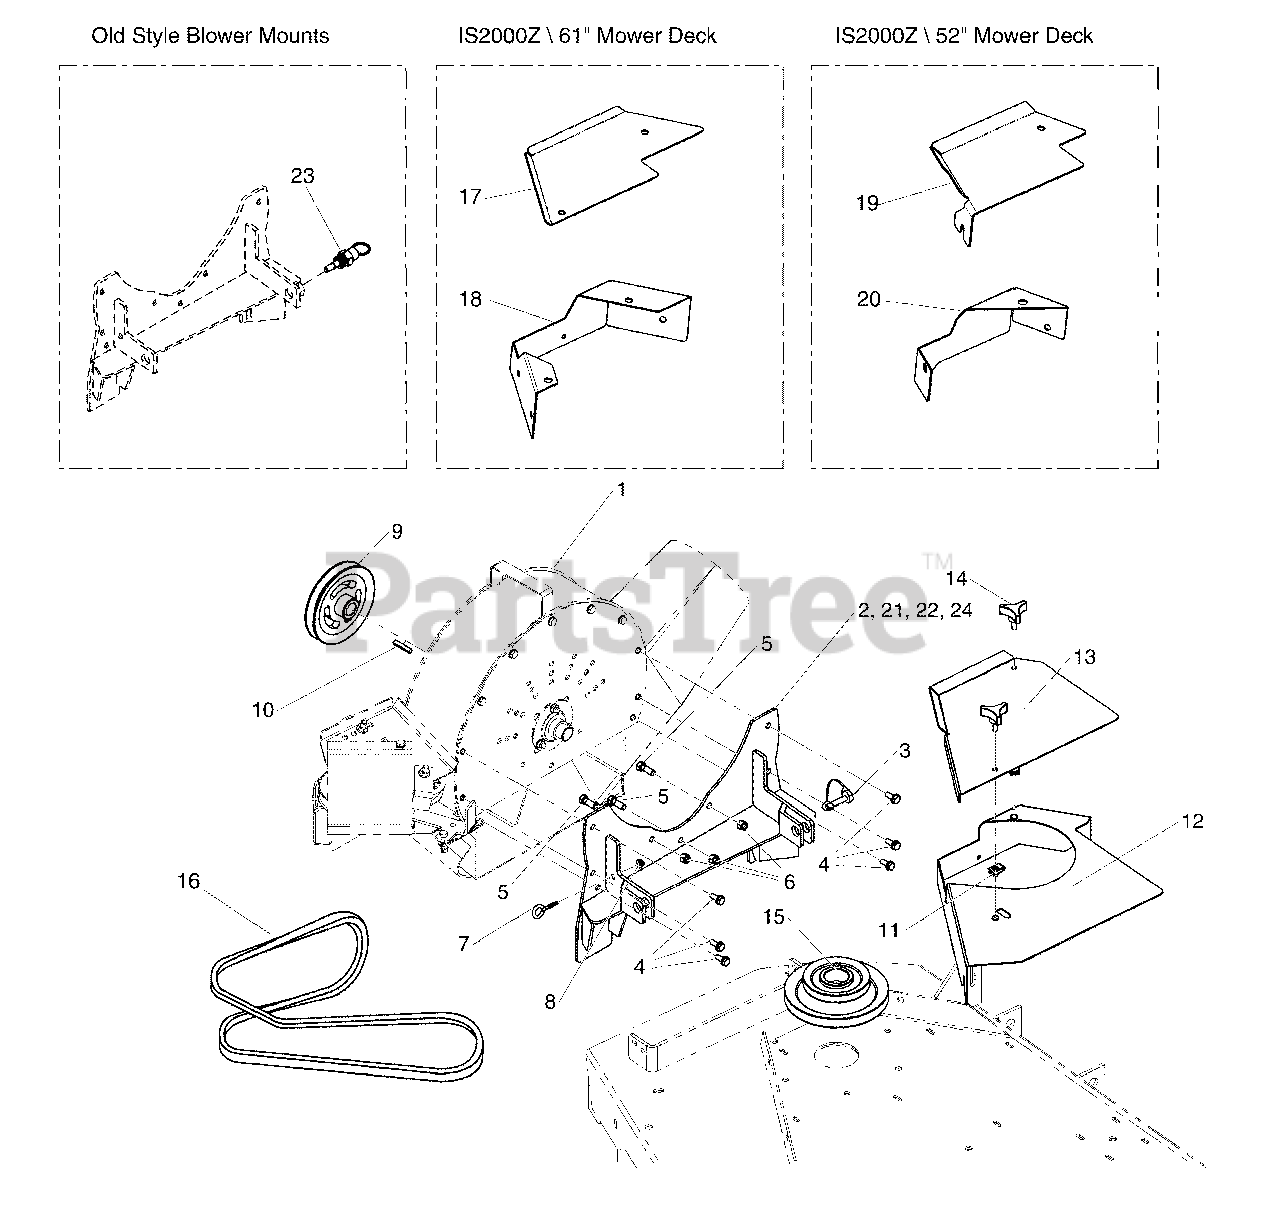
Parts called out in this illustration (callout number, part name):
1	BLOWER ASSEMBLY
2	WELD, BLOWER MOUNT 44 BLACK
2	WELD, BLOWER MOUNT, 48" BLACK
3	SNAPPERPIN, 5/16 X 2
4	BOLT, 5/16-18 X 3/4" SELF LOCK
5	BOLT, 3/8-16 X 1" GD5 YZ
6	NUT, 3/8-16 HEX NYLON LOCK
7	EYEBOLT, 1/4-20 X 2
8	NUT, 1/4-20 HEX NYLOCK FLANGE (5025391)
9	PULLEY, BLOWER AXLE, 44 & 48
9	PULLEY, BLOWER AXLE, 52
9	PULLEY, BLOWER AXLE, 61
10	KEY 1/4 SQ X 1 1/2 LONG
11	BODY CLIP, 5/16-18 X 1/2" DEEP
12	GUARD, DECK - BLACK
13	SHIELD, BELT
14	KNOB, PLASTIC, 5/16-18 X 3/4"`2``
15	PULLEY, BLOWER 48" DECK
15	PULLEY, BLOWER 52" DECK
15	PULLEY, BLOWER 61" DECK
16	BELT, # 7-3359
16	BELT, #7-6718, 92.0" E.L.
16	BELT, #7-6717, 88.8" E.L.
17	GUARD, BELT, 61", 2000 FASTVAC - BLK
18	GUARD, DECK, 61", 2000 FASTVAC - BLK
19	GUARD, BELT, 52",2000 FASTVAC - BLK
20	GUARD, DECK, 52",2000 FASTVAC - BLK
21	WELD, BLOWER MOUNT, 52" BLACK
22	WELD, BLOWER MOUNT, 61" BLACK
23	PIN, LATCH, SPRING LOADED - PULL ACTION
24	WELD, BLOWER MOUNT, 52" BLACK
